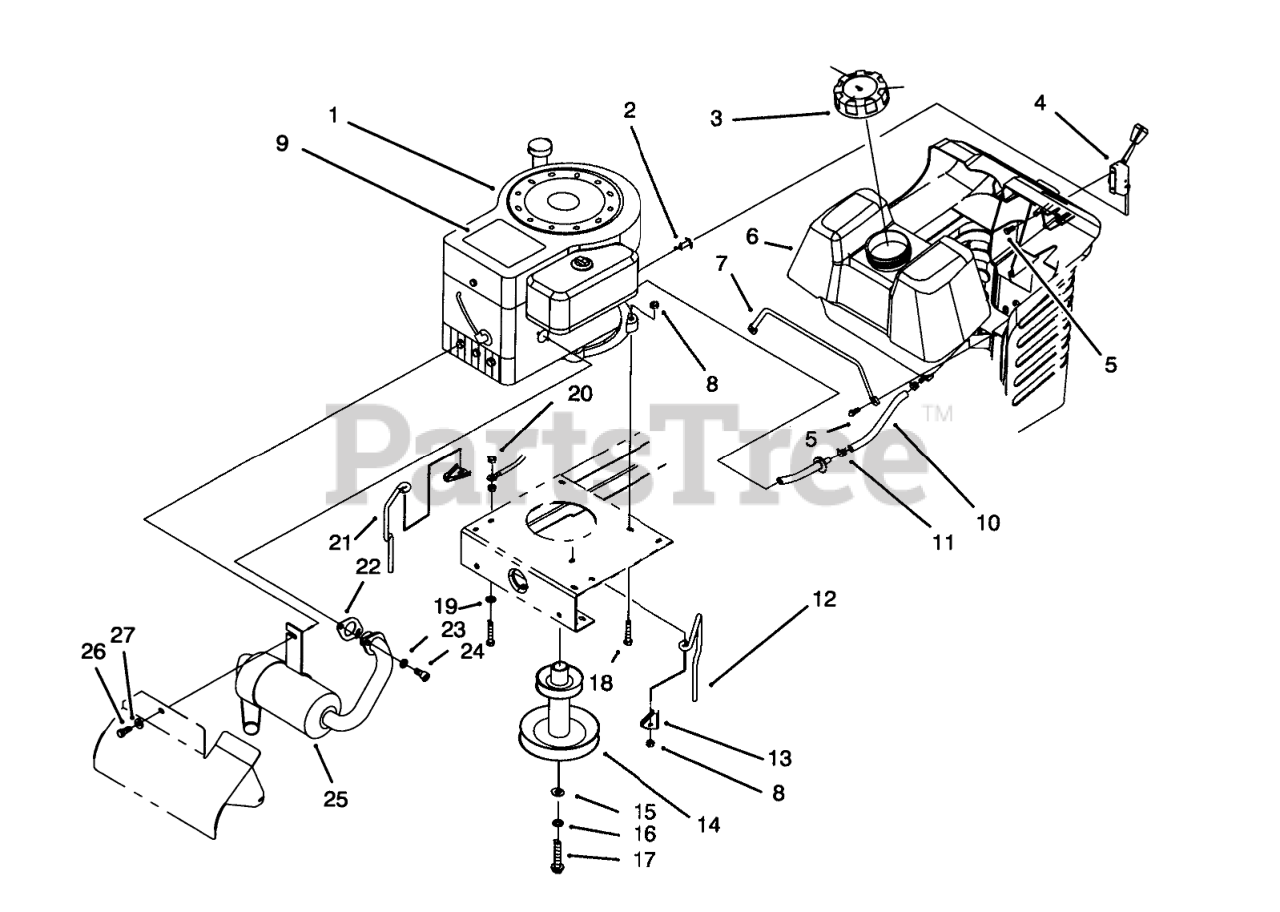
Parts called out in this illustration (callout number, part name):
1	Engine-12.5 H.P.
2	THROTTLE CABLE ASM
3	GAS CAP ASM
4	THROTTLE CONTROL ASM
5	SCREW-SPECIAL
6	GAS TANK ASM
7	GAS TANK ROD
8	NUT-LOCK, NI
9	DECAL - TORO QUIET 12.5
10	HOSE-FUEL
11	CLAMP-HOSE
12	LH BELT GUIDE
13	ANCHOR-GUIDE, BELT
14	ENGINE PULLEY
15	WASHER-FLAT
16	WASHER-LOCK
17	SCREW-HH
18	SCREW-HH
19	WASHER-LOCK
20	NUT-KEPS
21	RH BELT GUIDE
22	GASKET-EXHAUST
23	WASHER-LOCK
24	SCREW-HSH
25	MUFFLER
26	SCREW-HH
27	WASHER-LOCK
